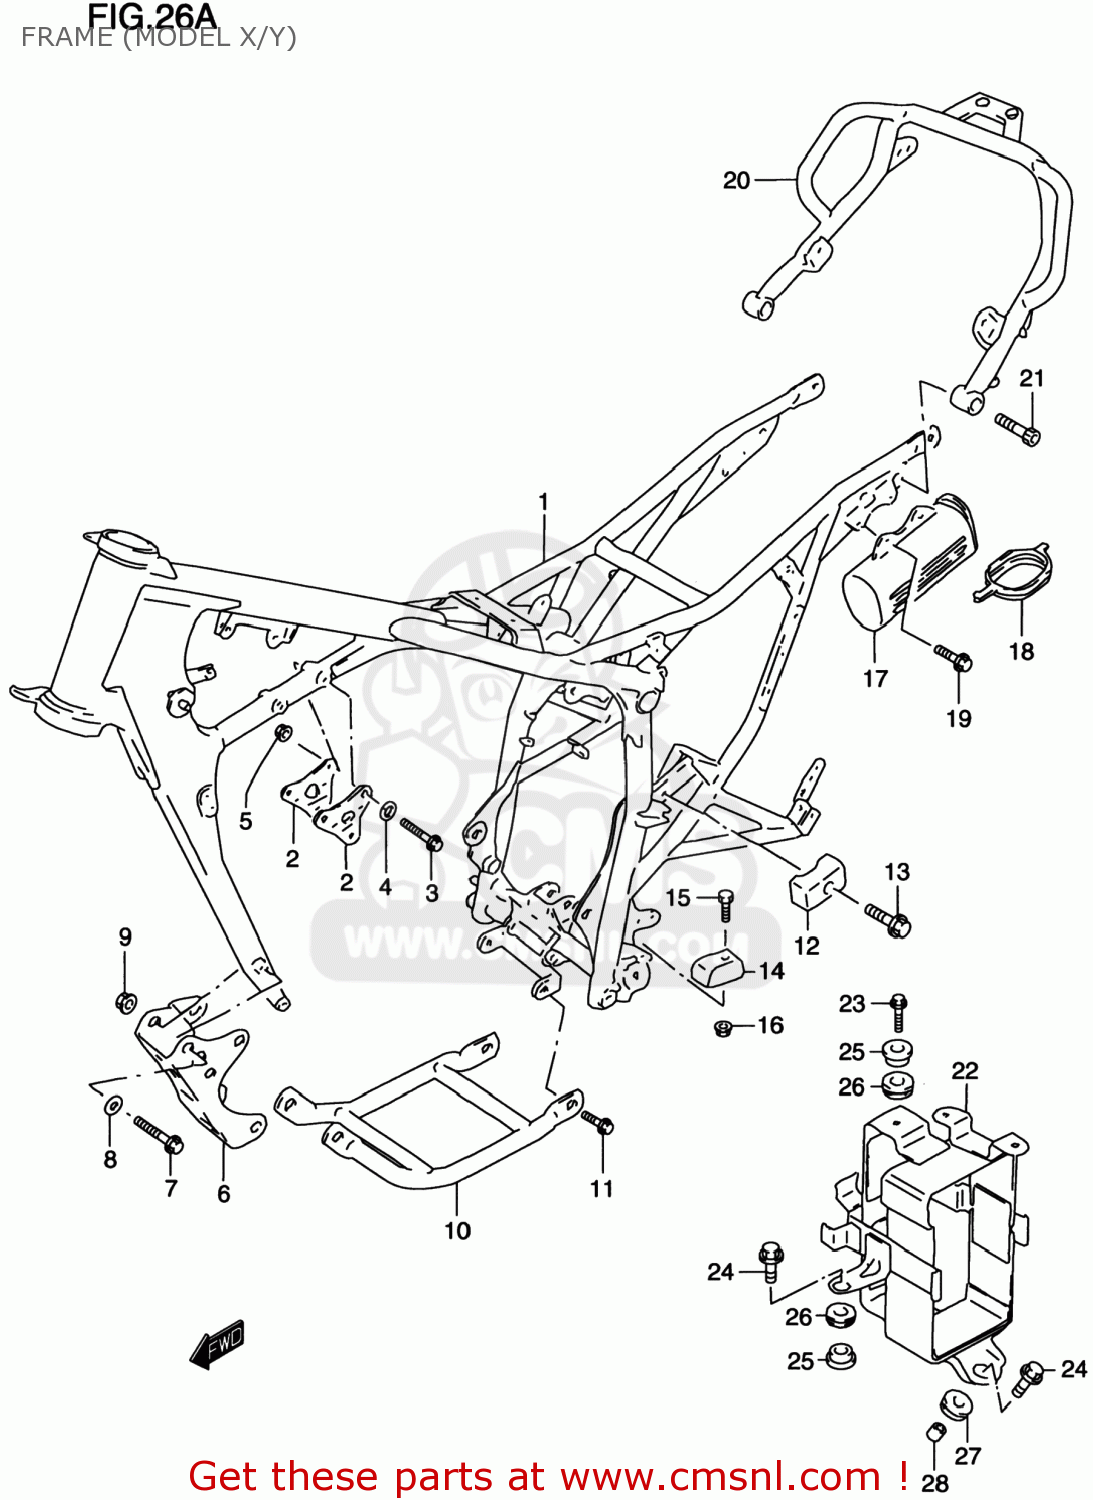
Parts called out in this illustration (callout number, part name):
1	FRAME COMP
2	PLATE,ENGINE MOUNT UPR
3	BOLT(8X53)
4	LOCK WASHER
5	NUT
6	PLATE,ENGINE MOUNT LWR
7	BOLT(8X65)
8	LOCK WASHER
9	NUT
10	PROTECTOR ENGINE(CHARCOAL)
11	BOLT
12	GUIDE,CH CONTROL UPR
13	BOLT
14	GUIDE,CHAIN CONTROL LWR
15	BOLT
16	NUT
17	HOLDER,TOOL
18	CAP,HOLDER
19	BOLT 6X16
20	GRIP,RR
21	BOLT(8X30)
22	HOLDER,BATTERY
23	BOLT
24	BOLT(6X25)
25	WASHER
26	CUSHION
27	CUSHION
28	SPACER(6.5X10X9)
